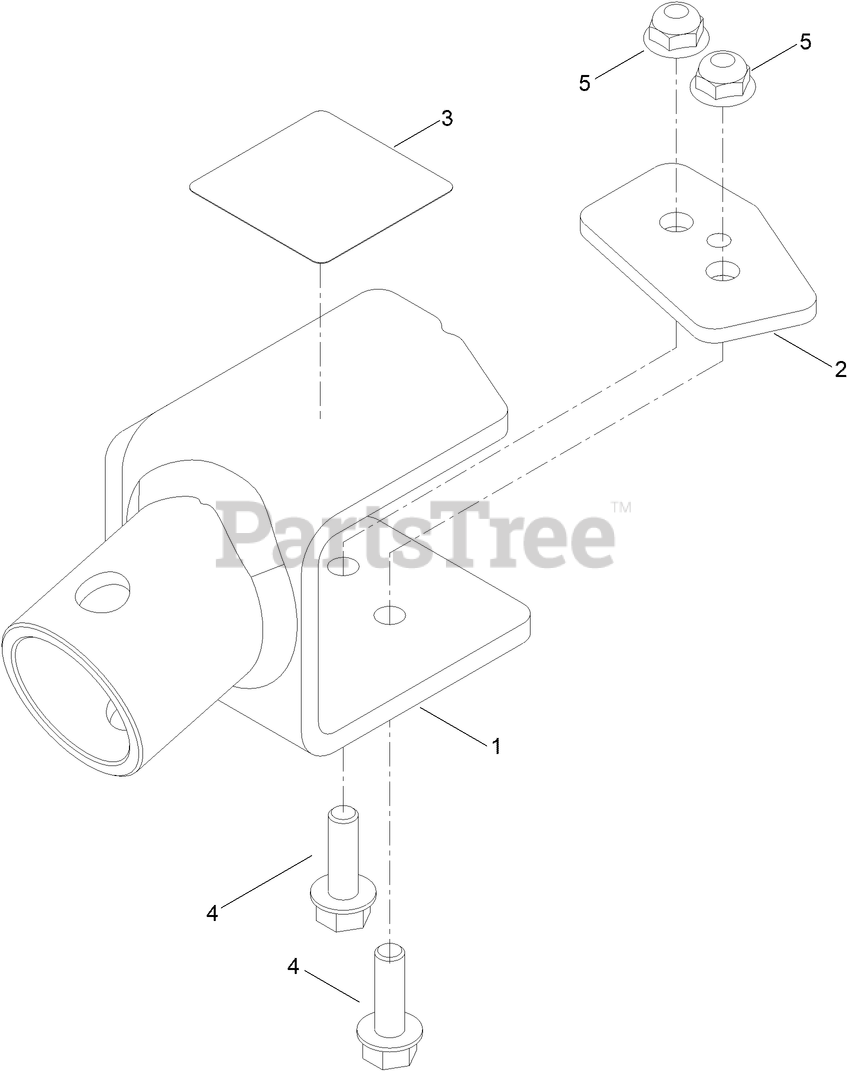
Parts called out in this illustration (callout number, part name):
1	MOUNT, JACK [RED]
2	PLATE, BACKER [RED]
3	DECAL-WARNING, JACK
4	SCREW-HHF
5	NUT-HF
